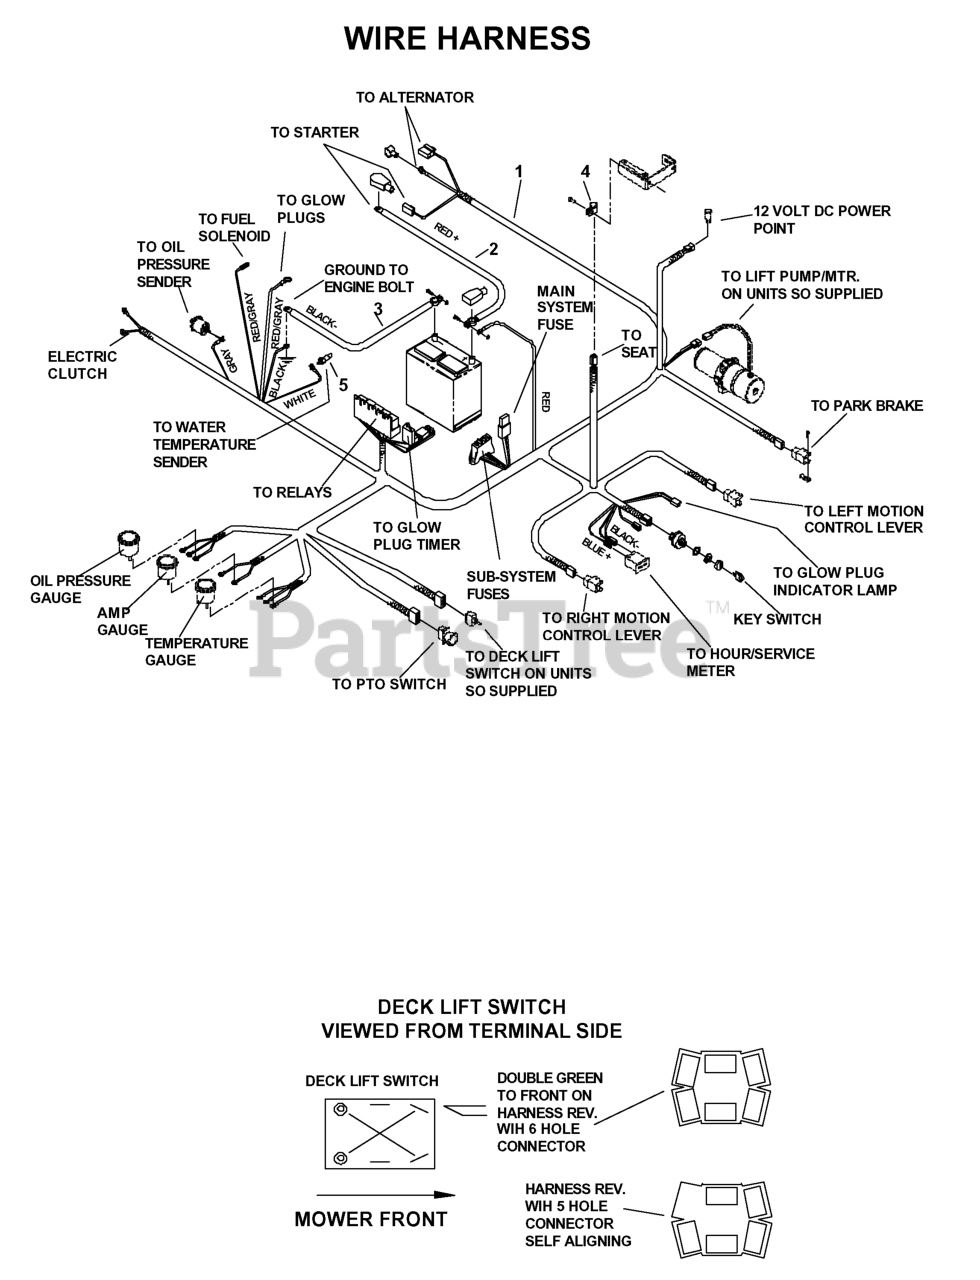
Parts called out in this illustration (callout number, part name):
1	HARNESS, ENG - B&SD DIESEL
2	CABLE, POS.
3	CABLE, NEG.
5	SENDER,TEMP
